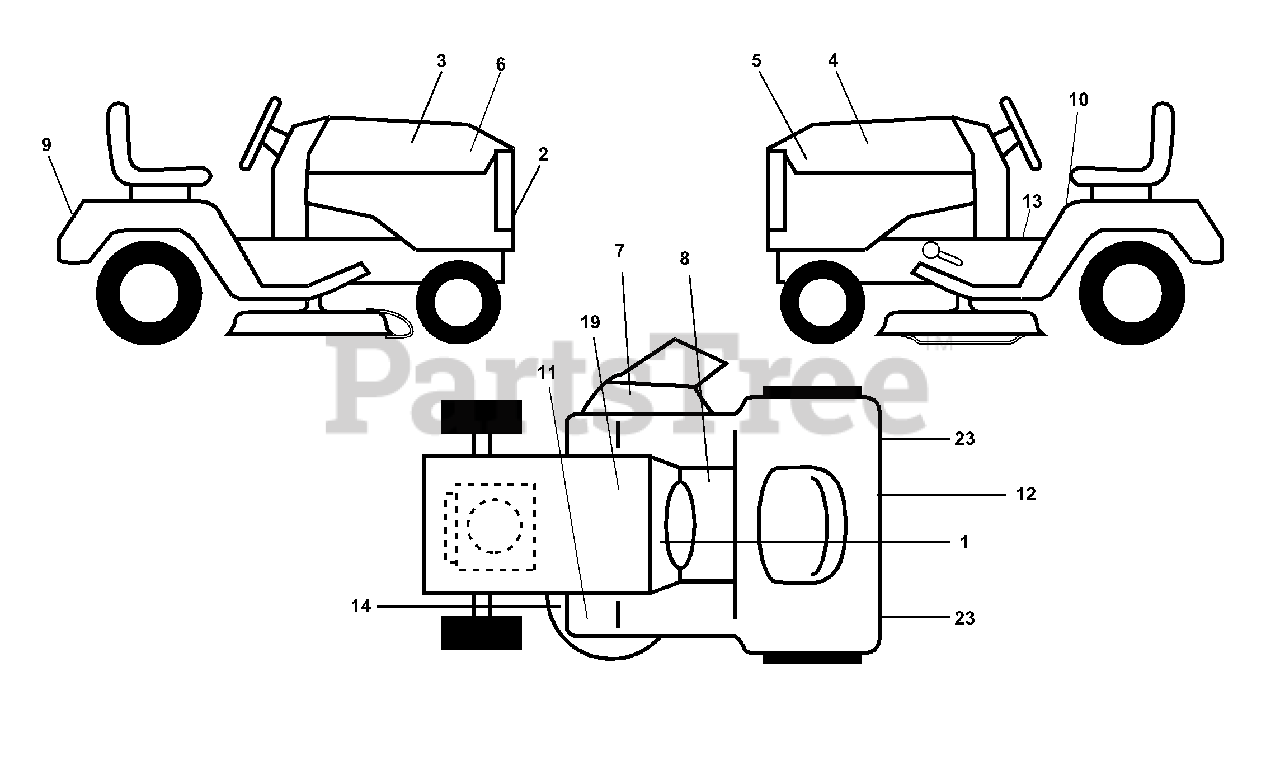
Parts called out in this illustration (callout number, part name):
1	Decal, Operating Instruction
2	Decal, Grille Husqvarna "H" Logo
3	Decal, Hood, RH
4	Decal, Hood, LH
5	Decal, Inst Hood LH GTH200 Hydro
6	Decal, Insrt Hood RH GTH200 Hydro
7	Decal, Warning Multi-Language
8	Decal, Brake Parking Saddle
9	Decal, Fender
10	Decal, Caution
11	Decal, Clutch/Brake
12	Decal, D-Bar Ctrl. Mvt Hyd YT/GT
13	Decal, Sdl Cold Start Hyd E/F
14	Decal, V-Belt Schematic
19	Decal, Battery
23	Reflector, Taillight
